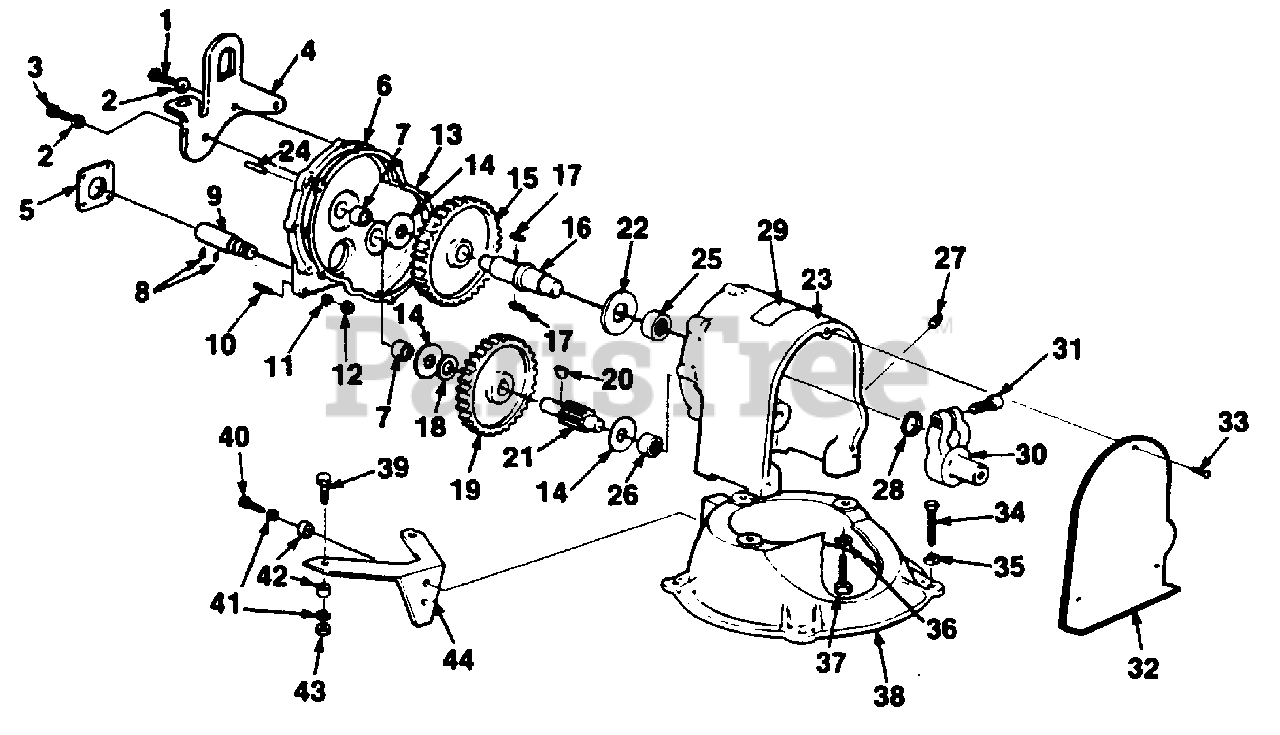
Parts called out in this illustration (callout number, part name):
1	SCREW- Hex hd (1/4-20 x 1 1/2")
2	WASHER- Lock (1/4")
3	SCREW- Hex hd (1/4-20 x 1 1/4")
4	BRACKET- Lift
5	GASKET- Engine mounting
6	COVER- Gear Case w/bearings
7	BEARING Needle
8	SCREW- Set, 10-32 x 3/8
9	SHAFT- Extension
10	STUD- 5/16-24, 5/16-18
11	WASHER- Lock (5/16")
12	NUT- 5/16-18
13	GASKET- Gear case
14	WASHER- Thrust, small
15	GEAR- Main
16	SHAFT Drive
20	KEY- Woodruff #61
21	SHAFT- Pinion
22	WASHER- Thrust large
23	CASE- Gear w/bearings
24	PIN- Dowel
25	BEARING- Needle
26	BEARING Needle
27	PLUG- Pipe
28	SEAL- Garlock
30	CRANK
31	SCREW- Cap (1/2-13 x 1 1/2")
32	SHIELD- Crank
33	SCREW- Thumb (1/4-20 x 1/2")
34	SCREW- Hex hd.
35	WASHER- Lock (3/8")
36	WASHER- Lock (1/2")
37	SCREW- Hex hd (1/2-13 x 1 3/4")
38	BODY Pump (upper)
39	SCREW- Hex hd (5/16-18 x 1 1/2") (111DP2-1)
40	SCREW- Hex hd (111DP2-1)
41	WASHER- Lock (5/16") (111DP2-1)
42	WASHER- Flat (111DP2-1)
43	NUT- (5/16-18) (111DP2-1)
44	SUPPORT Engine (111DP2-1)
